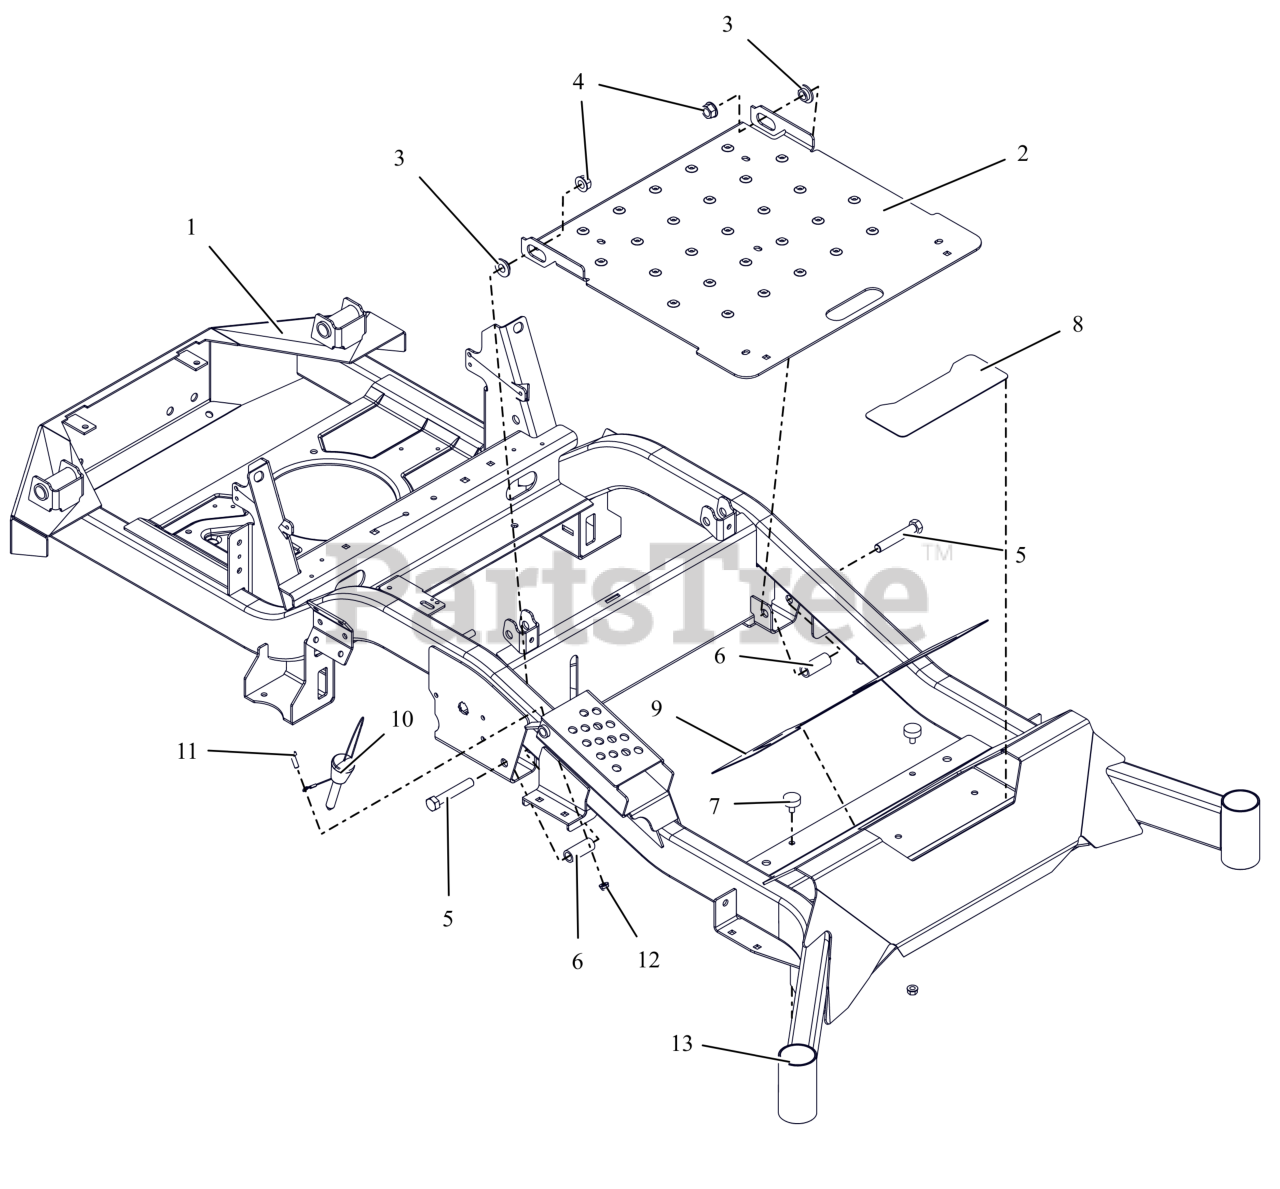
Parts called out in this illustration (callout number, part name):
1	APEX 60"FRAME W/SAFETY DECALS
2	PANEL, ACCESS
3	BSHG-FLG .515X.750X.395X1.120
4	NUT-LK-TOP-FLG .500-13 GF ZCC
5	BLT, HEX .50-13X3.00 G5 ZCC
6	SPACER, .515X.75X1.83
7	BUMPER, RUBBER
8	GRIP, STEP
9	GRIP, FRONT
10	PIN- MAGNETIC .50X2.70
11	BLT, HEX .25-20X.75 G5 ZCC
12	NUT,NYL-FLG .25-20 GF ZCC
13	NUT,SPNLK-FLG .31-18 G5 ZCC
